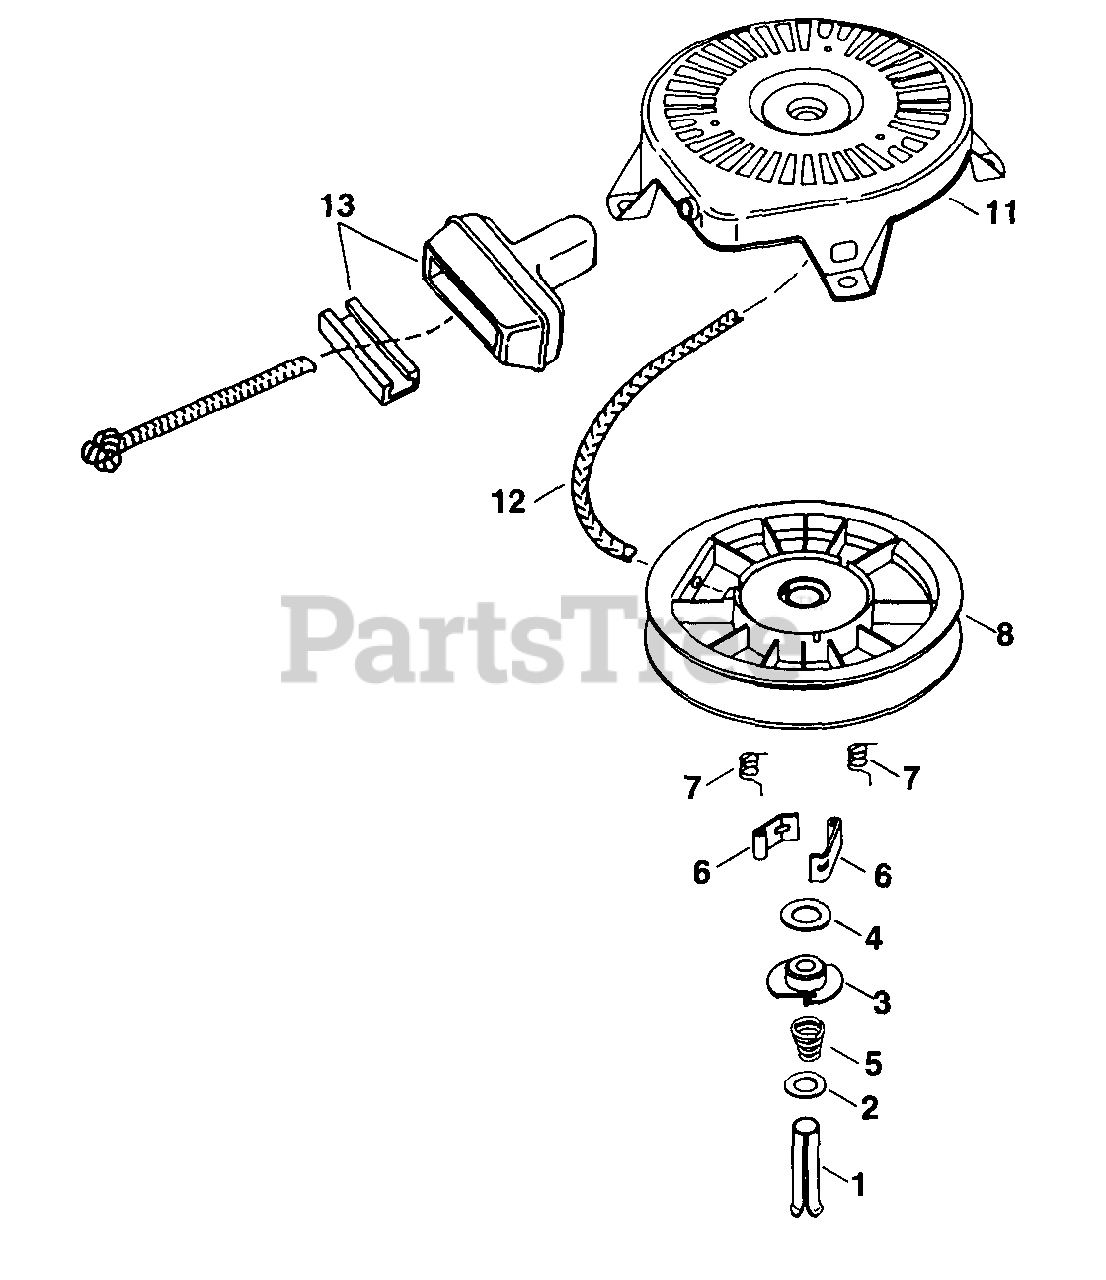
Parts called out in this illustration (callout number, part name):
1	Spring Pin
5	Brake Spring
6	Starter Dog
7	Dog Spring
8	Pulley & Rewind Spring Ass'y
11	Starter Housing Ass'y.
12	Starter Rope (Length 114" x 11/64" Dia.)
13	Starter Handle
